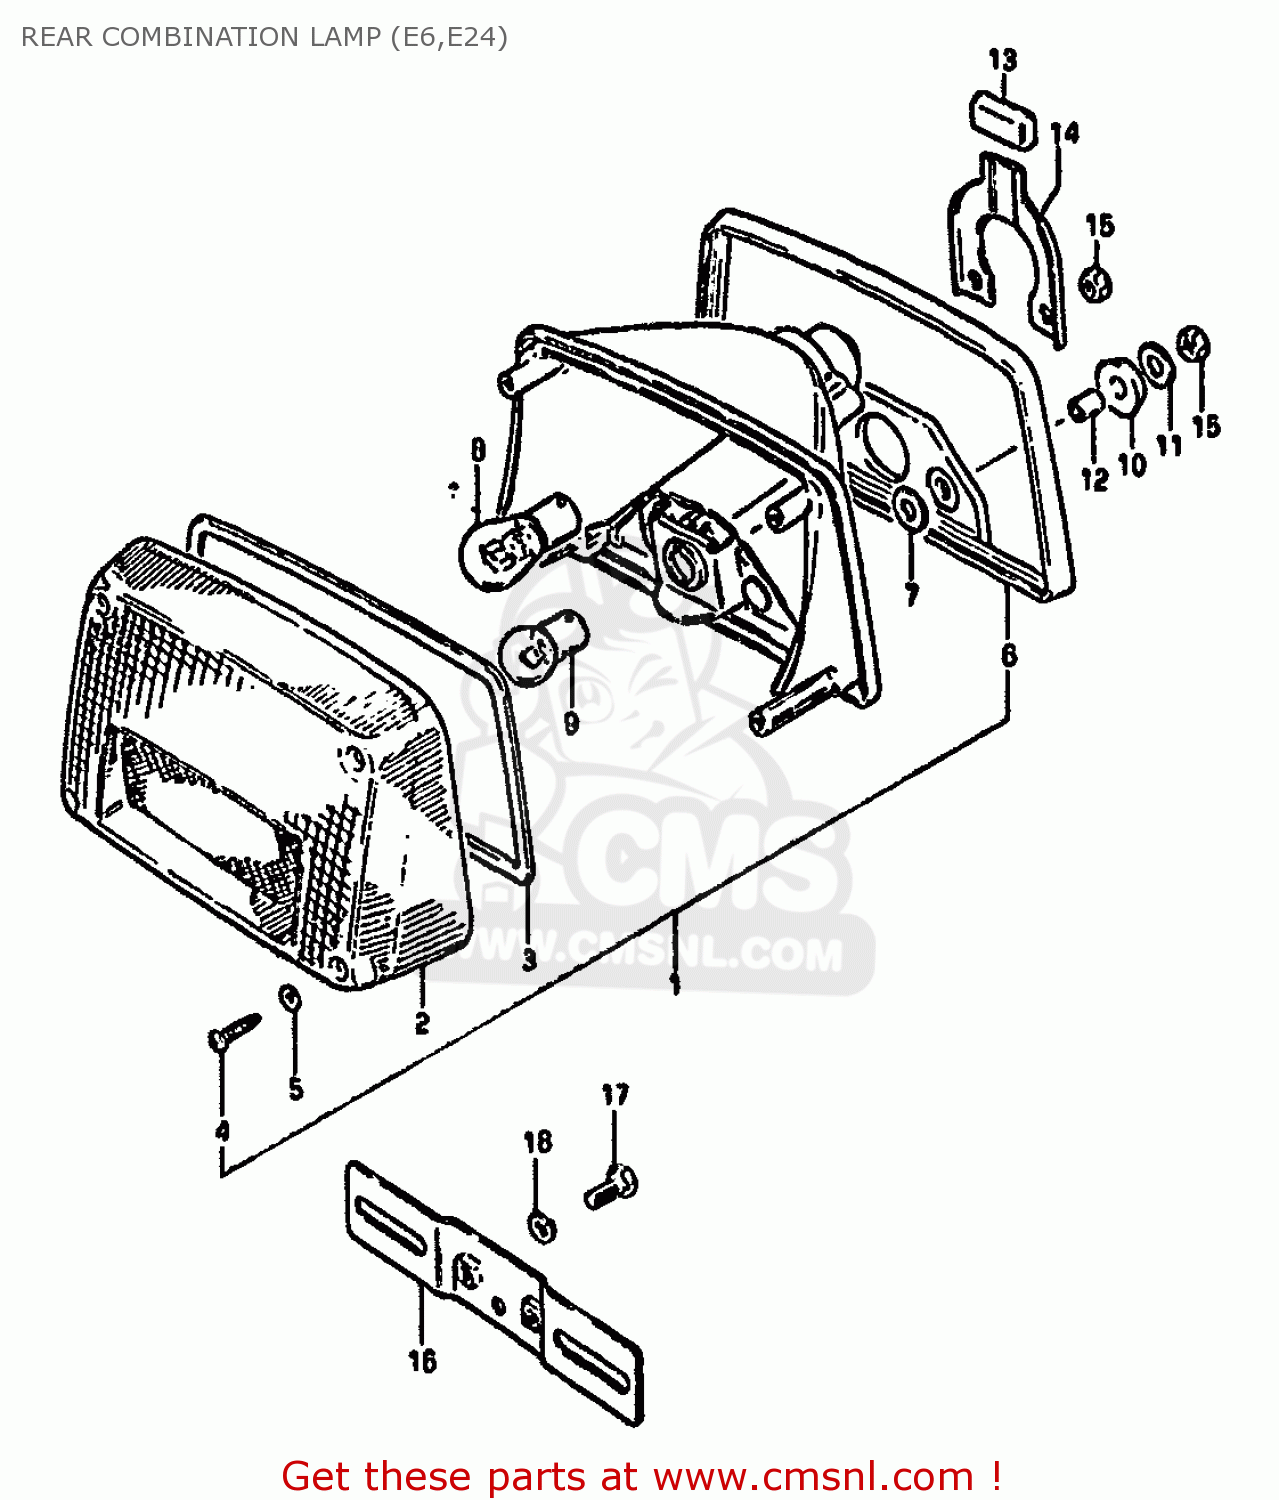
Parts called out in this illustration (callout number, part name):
1	LAMP ASSEMBLY,REAR COMBINATION
2	LENS
3	GASKET (NAS)
4	SCREW,REAR COMBINATION LAMP
5	GASKET (NAS)
6	CUSHION,REAR COMBINATION LAMP
7	WASHER,REAR COMBINATION LAMP
8	BULB(12V23W)
9	BULB
10	CUSHION,RR COMBINATION LAMP
11	WASHER
12	SPACER (6.4X9X10.5)
13	CUSHION,REAR COMBINATION LAMP
14	PLATE
15	NUT 6MM
16	BRACKET, LICENSE PLATE
17	BOLT
18	LOCK WASHER
